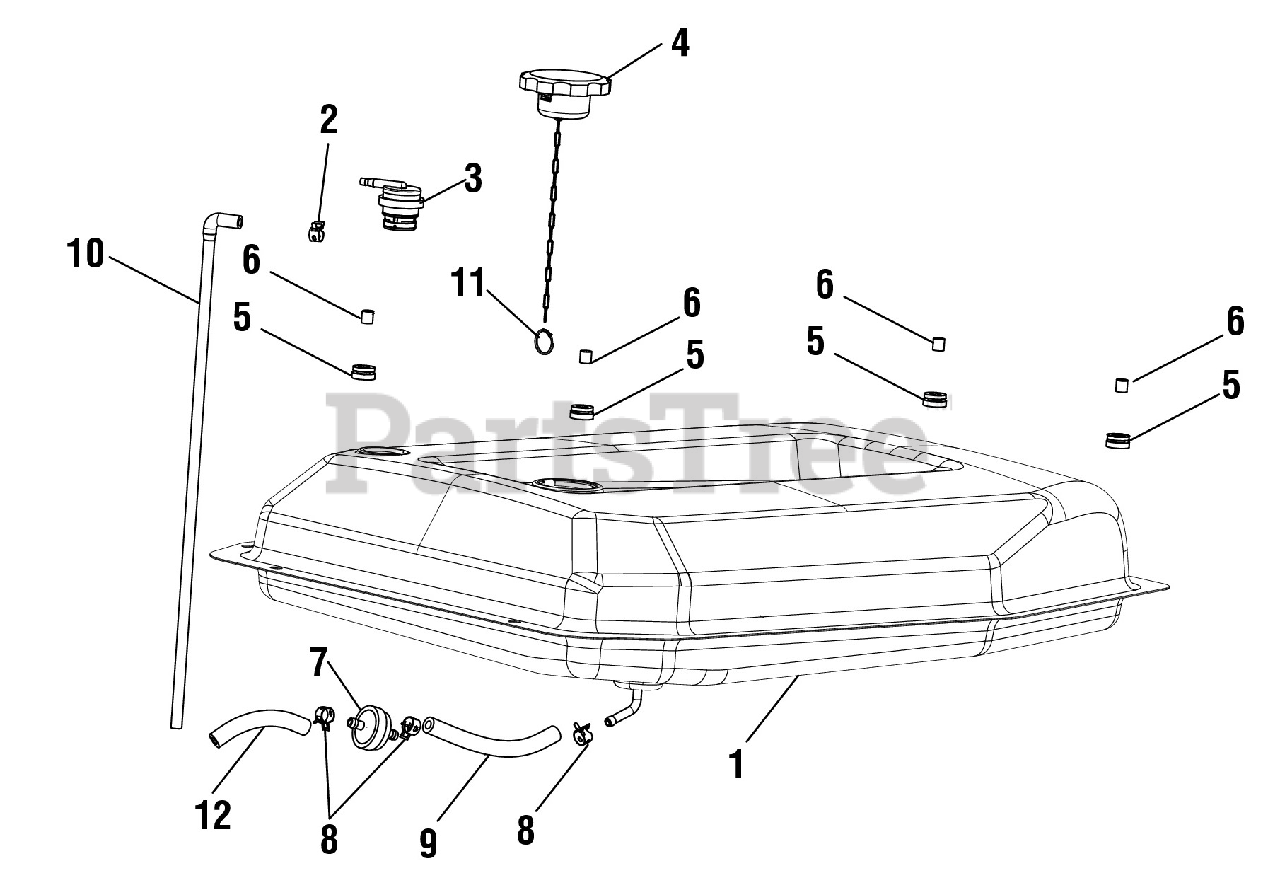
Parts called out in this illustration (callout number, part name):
1	Fuel Tank
2	Fuel Line Clamp (7/16 in., BM903611)
3	Fuel Tank Vapor Vent
4	Fuel Cap Assembly
5	Bushing (Fuel Tank Isolator)
6	Spacer (Fuel Tank Isolator)
7	Fuel Filter Inline (1/4 in.)
8	Fuel Line Clamp (1/2 in.).
9	Fuel Hose (175 mm)
10	Vapor Hose
11	Ring Clip
12	Fuel Hose (85 mm)
